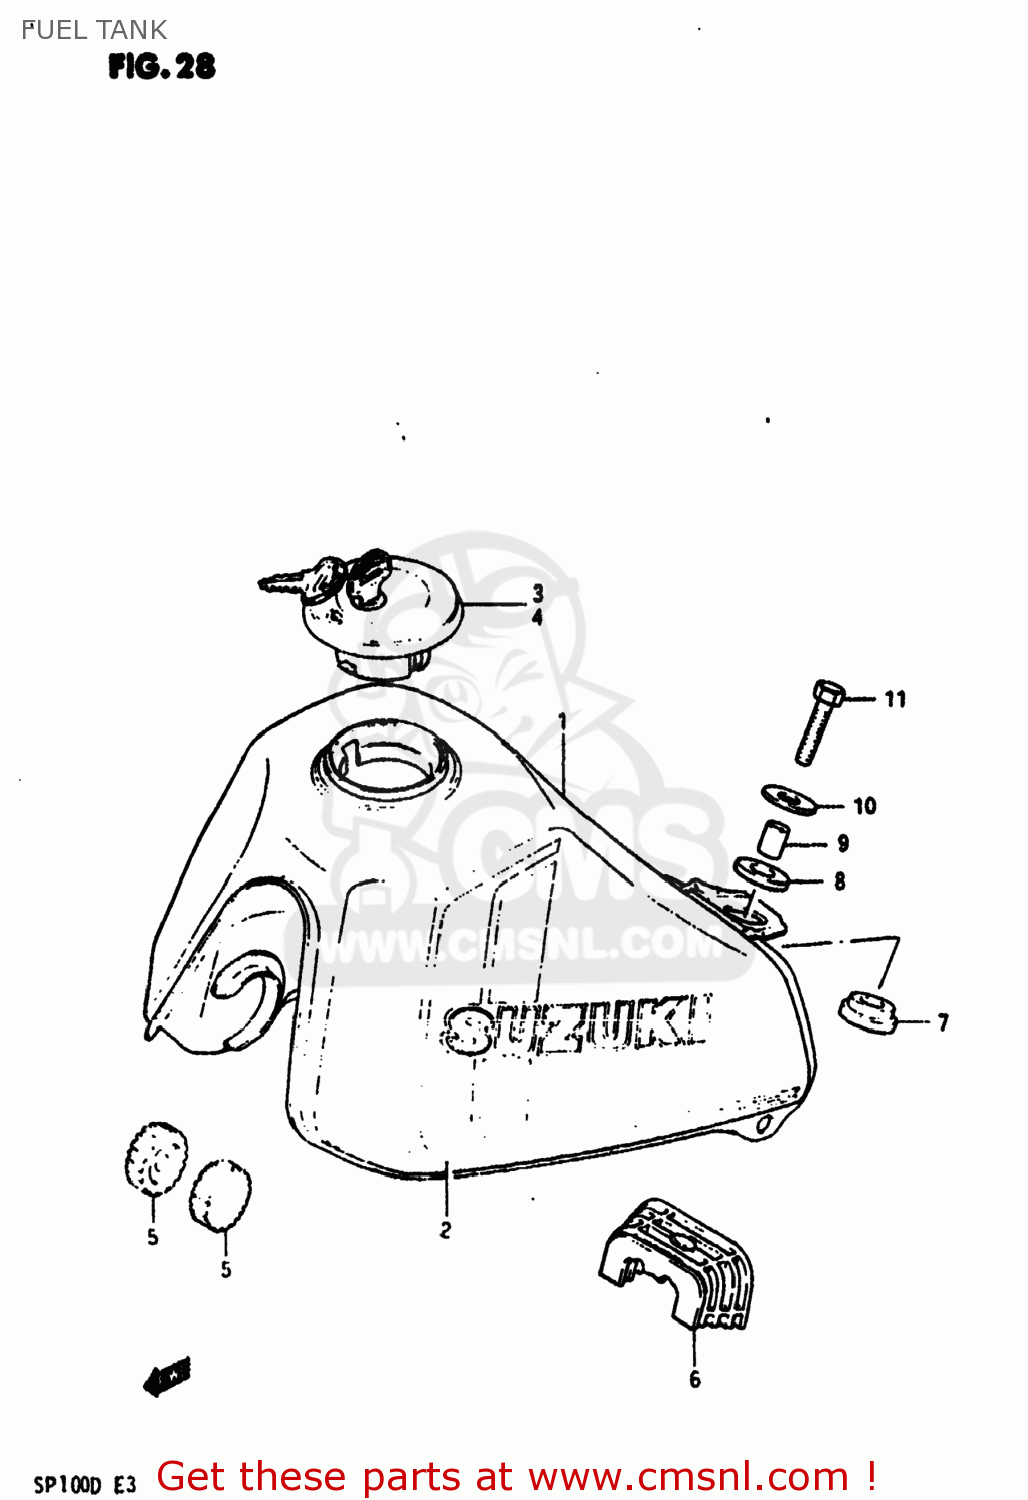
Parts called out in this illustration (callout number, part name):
1	TANK ASSEMBLY,FUEL
2	TAPE SET,FUEL TANK
3	CAP SET,FUEL TANK
4	CAP SET,FUEL TANK
5	CUSHION
6	CUSHION,FUEL TANK
7	CUSHION
8	CUSHION
9	SPACER(8.5X12X19)
10	WASHER (8.5X29X1.6)
11	BOLT (8X30)
